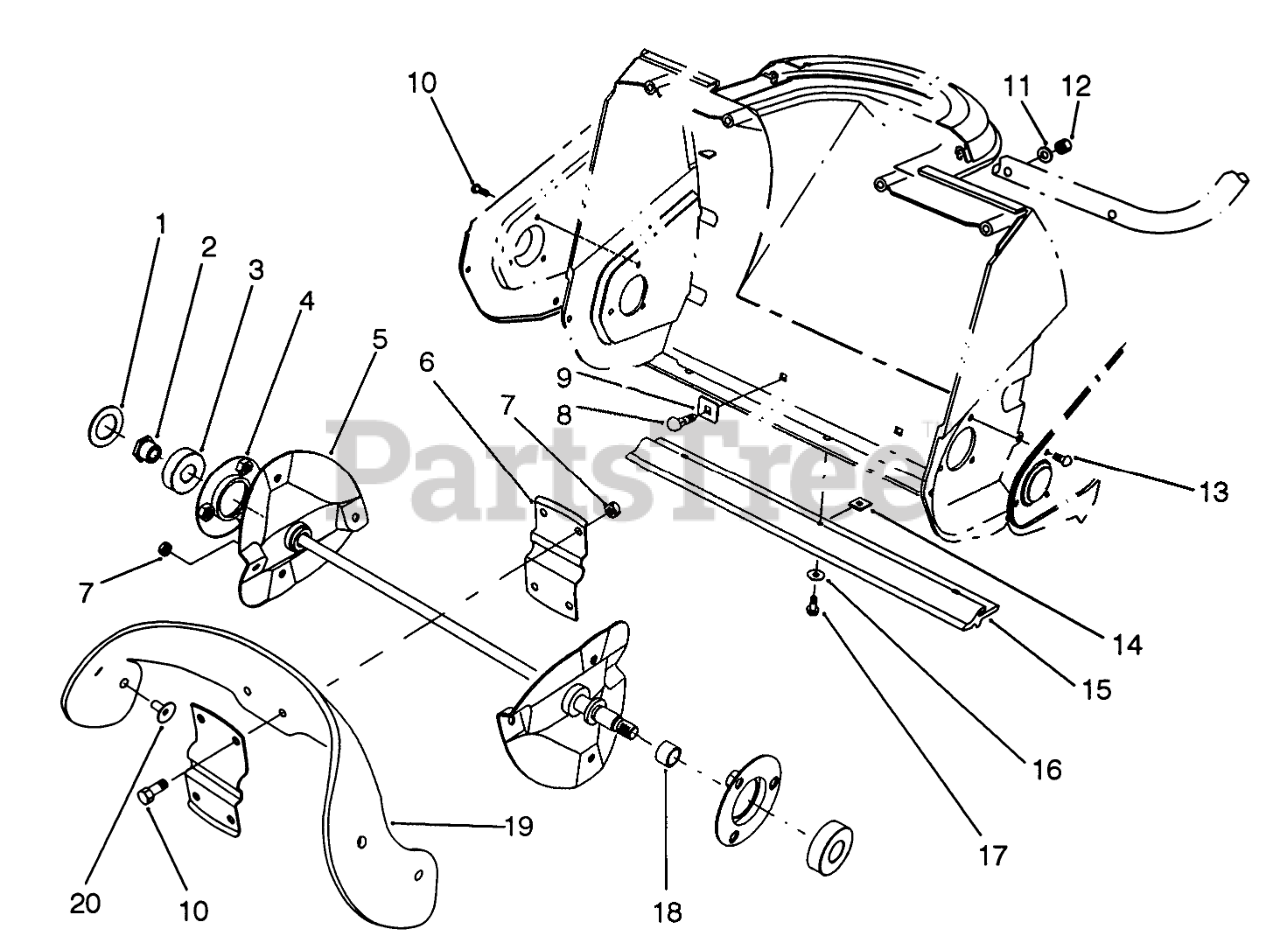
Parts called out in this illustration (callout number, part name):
1	WASHER-RUBBER
3	BEARING-BALL
4	FLANGE BEARING ASM
5	Rotor
6	Support-Rotor
7	NUT-LOCK, NI
8	SCREW-CARR
9	WASHER-SQUARE
10	SCREW-HHF
11	WASHER
12	NUT-LOCK, NI
13	SCREW-HH
14	NUT-CLIP, U
15	SCRAPER
16	WASHER-FLAT
17	SCREW-HWHTF
18	SPACER
19	BLADE-ROTOR
20	SCREW
